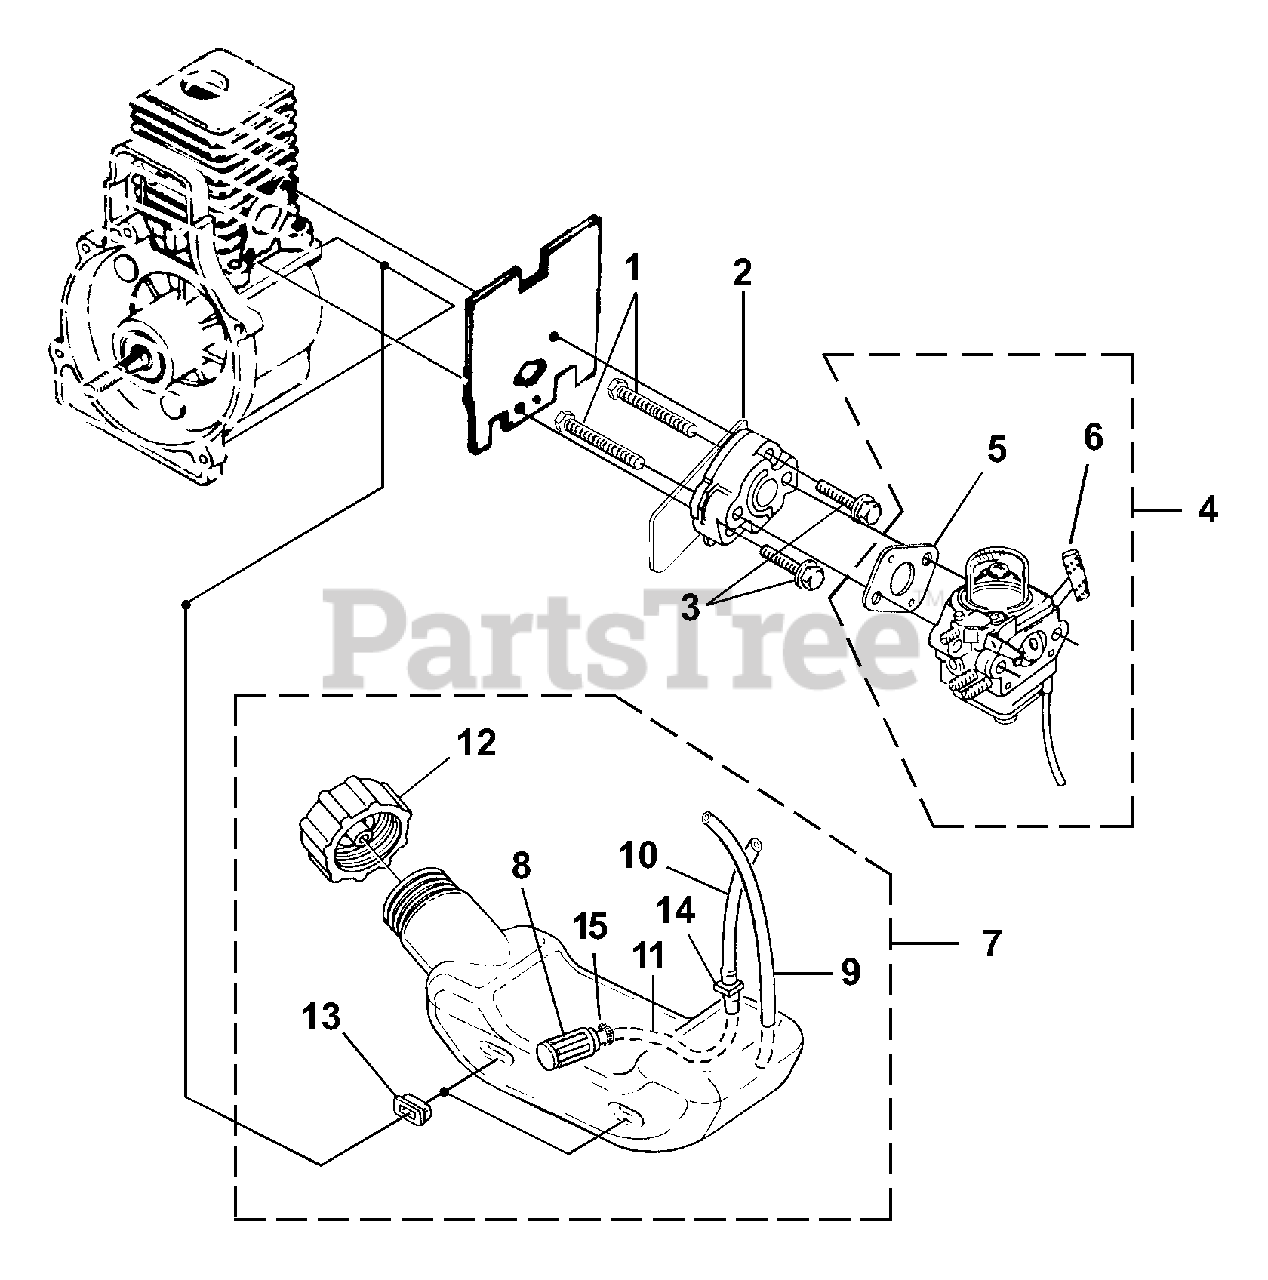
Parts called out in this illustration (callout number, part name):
1	SCREW-Machine (10-24 X 2 1/4")
2	HEAT DAM
3	SCREW-Sems (10-24 X 1")
4	CARBURETOR KIT
5	GASKET-Carburetor
6	LEVER-Choke (Zama)
7	FUEL TANK ASSY.
8	FILTER-Fuel
9	TUBING-Rubber
10	TUBING-Rubber
11	TUBING-Rubber
12	FUEL CAP
13	BUMPER-Rubber
14	FITTING-Inline
15	CLAMP
